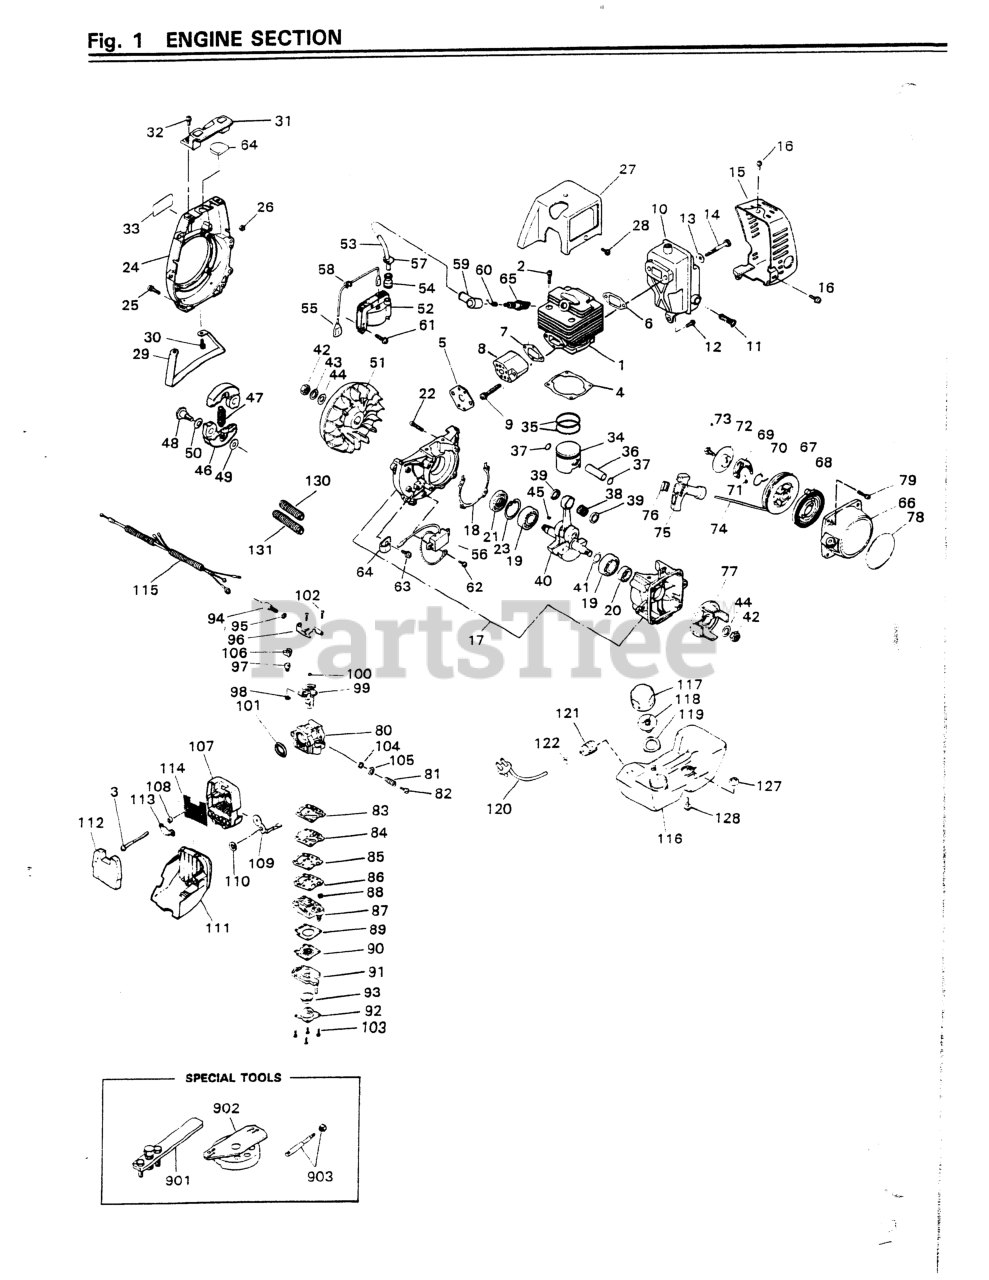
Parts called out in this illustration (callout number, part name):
3	SCREW, M5 X 55
9	SCREW, M5 X 40
10	MUFFLER (RPLS -15100)
11	ARRESTER
13	WASHER, FLAT (USE 182303)
14	BOLT, M6 x 65
15	COVER (RPLS -15410)
17	CASE COMPLETE
20	SEAL, OIL - STARTER SIDE
22	SCREW, M5 x 30(RPLS 0263-00530
23	RING, SNAP, M35 X 1.5
25	SCREW, M5 X 20
29	STAND
31	HEAD GUARD
32	SCREW (USE 0263-90520 )
34	PISTON (NLA)
35	RING, PISTON (RPLS -41210)
36	PIN, PISTON
37	RING, SNAP
38	BEARING
39	WASHER (RPLS 1491-41510)
41	SHIM (REPLACES 848-870-G000)
43	WASHER, M10 X 25
44	WASHER, M10 x 1.6
45	KEY
47	SPRING, CLUTCH
48	SCREW
49	WASHER
50	WASHER (USE -51241)
53	CORD
54	CAP
59	CAP, PLUG
60	SPRING PLUG (RPLS 3310-71320)
61	SCREW (USE 0263-90520 )
62	SCREW, M5 X 14
63	SCREW, M5 x 10
64	CLAMP
66	RECOIL ASSEMBLY
67	REEL (NLA)
68	SPRING, SPIRAL (NLA)
69	RATCHET
70	SPRING (NLA) (REPLACES -75250)
71	SPRING, DOG (NLA)
72	RETAINER (NLA)
74	ROPE
75	KNOB
77	PULLEY (NLA) (RPLS -75210)
79	SCREW (USE 0263-90520 )
81	SHAFT ASSEMBLY
83	GASKET, PUMP
84	DIAPHRAGM
85	PLATE, PUMP (NLA)
86	GASKET, PLATE
87	KIT ONLY
89	KIT ONLY
90	DIAPHRAGM (USE 4810-81260)
91	BODY
92	COVER
93	PUMP, PRIMING
94	SCREW, CABLE
95	NUT, CABLE ADJUSTER
97	SWIVEL
98	RING
99	VALVE ASSEMBLY
101	RING, PACKING
102	SCREW
103	SCREW
106	CAP, CABLE END
108	SLEEVE
111	COVER, AIR FILTER (RPLS -82201
113	PLATE
115	CABLE (NLA) (RPLS -83101)
118	VALVE, VENT
121	FILTER ASSY
122	CLIP (REPLACES 2841-31280)
128	SCREW
902	SET BLOCK (TOOL)
903	ROD ASSEMBLY (TOOL)
